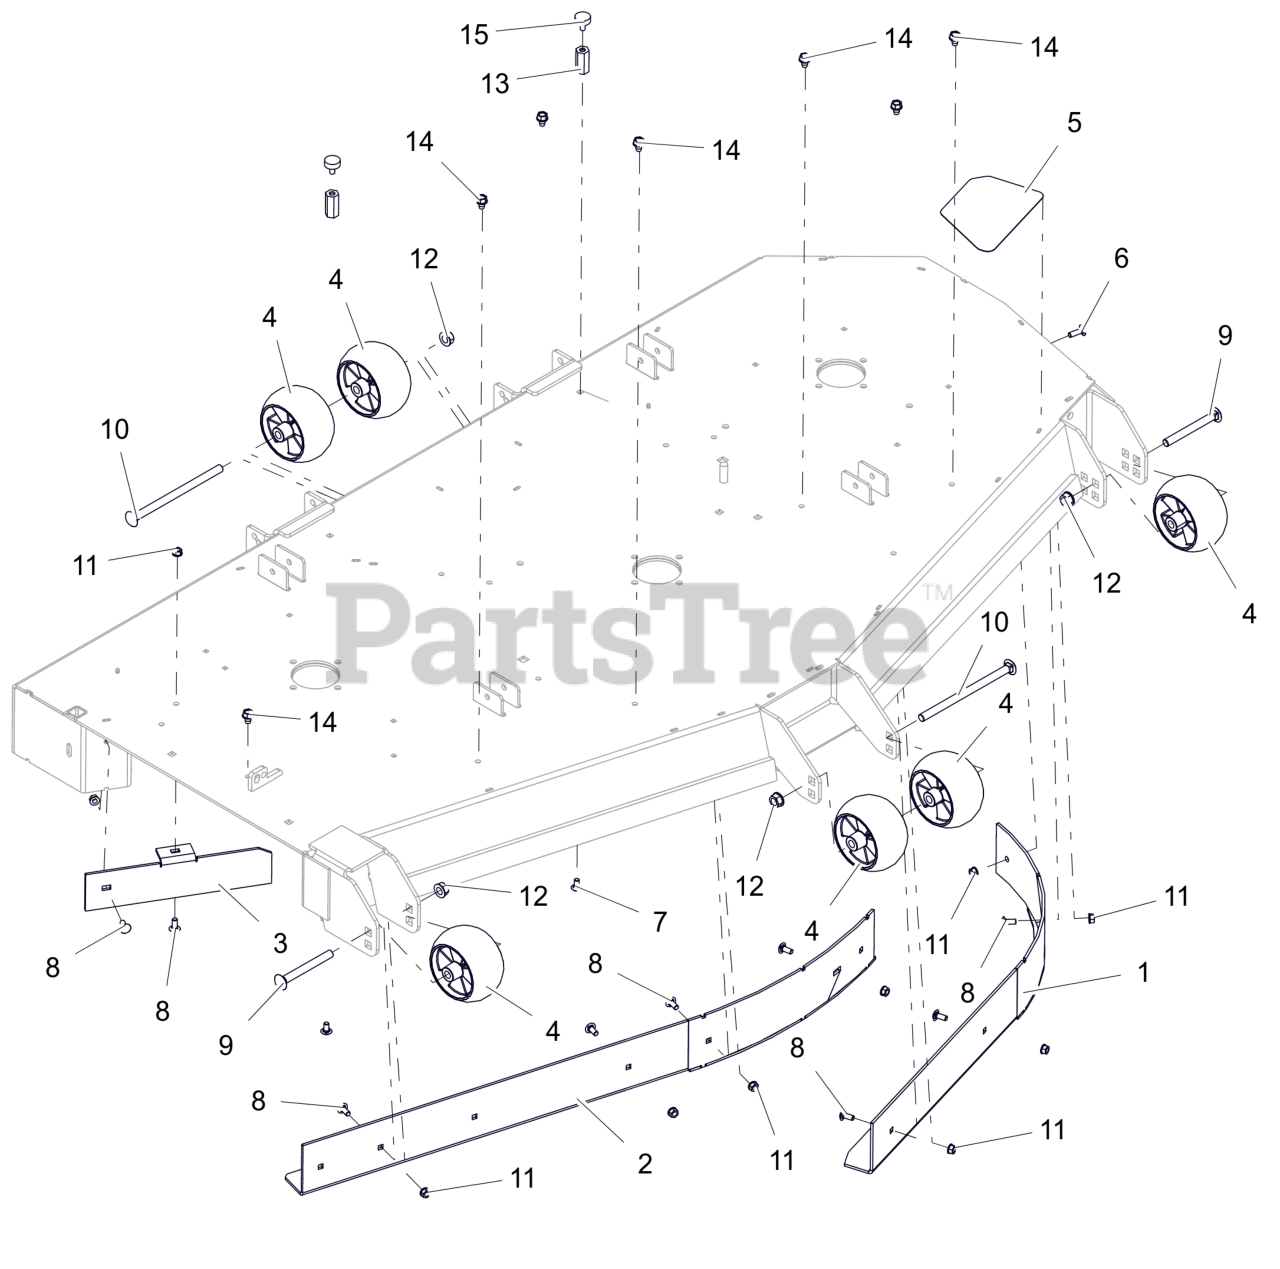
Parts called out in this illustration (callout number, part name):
1	WLDMT, 72" LH VACUUM BAFFLE (RED)
2	WLDMT, VACUUM BAFFLE 72" RH (RED)
3	72" DISCHARGE BAFFLE - RED
4	WHEEL, ANTI SCALP - 5X3 CTR W/RIBS
5	GRIP, STEP ANTI SKID
6	BLT,RHSSN .31-18X1.00 G5 ZCC
7	BTL,RHSSN .313-18 X 0.625 G5 ZCC
8	BLT, RHSSN.31-18X.750 G5 ZCC
9	BLT,RHNS .50-13X4.50 G5 ZCC NS
10	BLT,RHSN .50-13X8.00 G5 ZCC NS
11	NUT,LK-CTR-FLG .31-18 GF ZCC
12	NUT-LK-CTR-FLG .500-13 GG ZCC
13	NUT, COUPLING .312-18 X 1.625
14	SCR,TAP .375-16X.50 HWH TR ZCC
15	BUMPER, RUBBER
